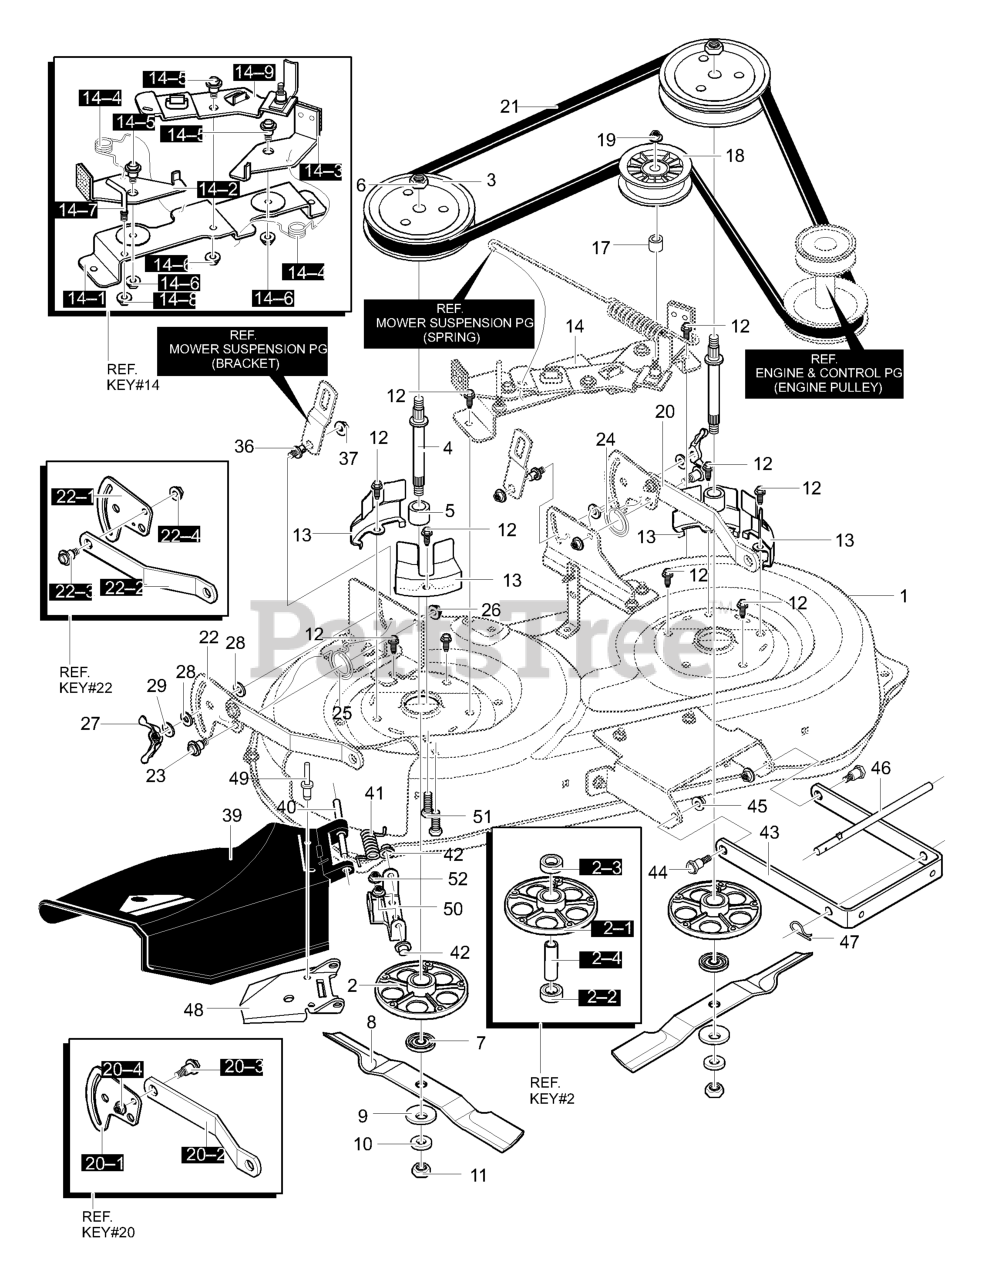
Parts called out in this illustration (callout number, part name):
1	Mower Deck Assembly
2	Jackshaft Assembly
2-1	Jackshaft Housing
2-2	Bearing, Upper
2-3	Bearing, Lower
3	Pulley, Quill
4	Jackshaft
6	Nut, 9/16-18
7	Adapter, Blade
8	Blade, 38 inches
10	Flat washer
11	Nut, .56-18 Regular
12	Engine Bolt 3/8x1.25
13	Cover, Segment Belt Guide
14	Asm. Brake with Support
14-1	Bracket, Brake Mtg
14-2	Assy, Brake RH
14-3	Assy, Brake LH
14-4	Torsion Spring
14-5	Bolt, Shoulder 3/8-16
14-6	Nut, 3/8-16 Mack
14-7	Screw - Guide
14-8	Nut, 5/16-18 Hex
14-9	Assy., Idler Arm
17	Spacer, 1/2 to 17MM
18	Idler Pulley
19	Nut, 3/8-16 Hwdfllk Mack
20	Asm., Plate Rear Sus. Brkt LH
20-1	Plate-Suspension
20-2	Suspension Bracket Rear
20-3	Bolt, Shoulder
20-4	Nut, 3/8-16
21	Belt, Barback Cl 84.24
22	Assy, Plate,Rear Sus Bkt RH
22-1	Plate-Suspension
22-2	Suspension Bracket Rear
22-3	Bolt, Shoulder
22-4	Nut, 3/8-16
23	Bolt, Shoulder
24	Spring, Torsion LH
25	Spring, Torsion RH
26	Nut, 3/8-16
27	Wingnut, 5/16-18
28	Pad, Friction
29	Washer
36	Pin, Hanger
37	Nut, 3/8-16
39	Deflector Chute
40	Asm., Bracket Idler
41	Spring, Torsion
42	Nut, Push Cap
43	Bracket, Frt Suspension
44	Shoulder Bolt
45	Nut, 3/8-16 Wdfllk Mack
46	Rod, Hanger
47	Hair Pin
48	Deflector Support
49	Rivet- Semi
50	Bracket, Chute Attach
51	Carr. Bolt, 5/16-18x.63
52	Nut, 5/16-18 Wdfllk
